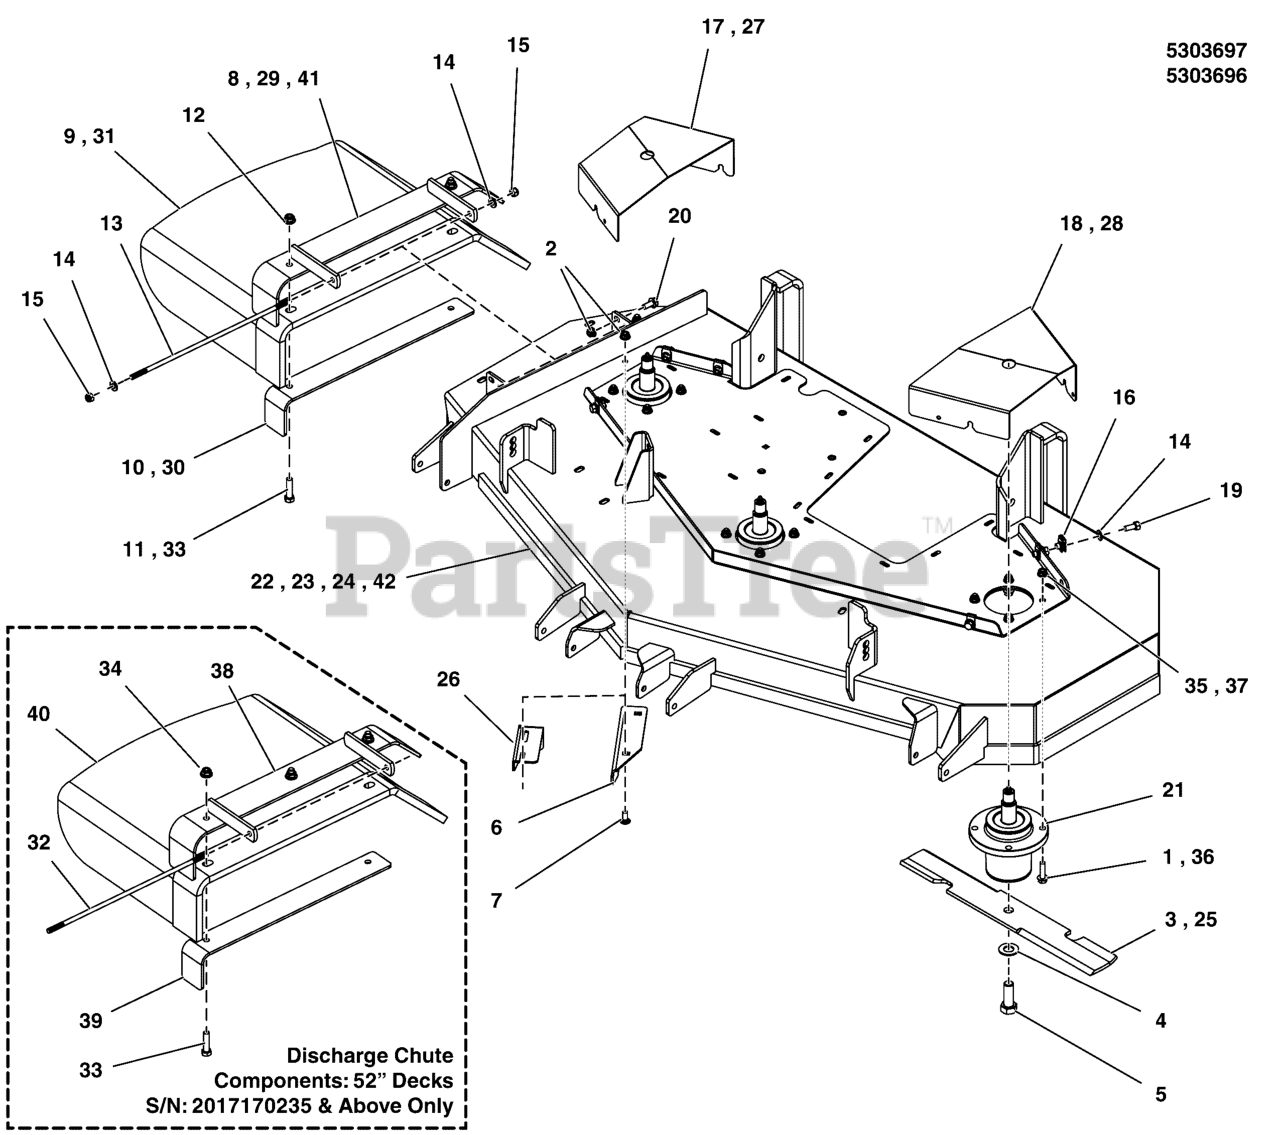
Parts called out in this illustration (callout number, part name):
1	BOLT, 5/16-18 X 1 1/4 FLANGE
2	NUT, 5/16-18 HEX NYLOCK FLANGE
3	BLADE, SET OF THREE
4	WASHER, BLADE BOLT, 9/16" F436, CZ
5	BOLT, 5/8-11 X 1-3/4 GD8
6	PLATE, DEFLECTOR, 52 DECK - BLK
7	BOLT, 5/16-18 X 3/4, CARRIAGE
8	WELD, MOUNT, DISCHARGE CHUTE - BLK
9	CHUTE, DISCHARGE, BEND RUBBER, 44/48/52 (5100842)
10	SUPPORT, DISCHARGE CHUTE, 48/52 - BLK
11	BOLT, 3/8-16 X 1-1/2" GD5 CZ
12	NUT, 3/8-16 HEX NYLOCK FLANGE
13	ROD, 5/16 X 13.75, TBE, CZ
14	WASHER, 5/16" SAE
15	NUT, 5/16-24 HEX NYLON LOCK
16	BODY CLIP, 5/16-18-7GA MATERIAL
17	GUARD, DECK, 52, RH - RED
18	GUARD, DECK, 52, LH - RED
19	BOLT, 5/16-18 X 3/4 GD5
20	BOLT, 5/16-18 X 3/4 GD5
21	ASSM, SPINDLE, LOW PROFILE
22	DECK SHELL W/ DECALS, 52, FW35 (5412132B)
23	DECK SHELL W/ DECALS, 48, FW35 (5412136B)
24	DECK SHELL W/ DECALS, 52, FW35SD-DOM (5414488B)
25	BLADES, SET OF THREE (3); 16.25 X.25 X 2.5, 1 X 3.5
26	PLATE, DEFLECTOR - BLK
27	GUARD, DECK, 48, RH - RED
28	GUARD, DECK, 48, LH -RED
29	WELD, MOUNT, DISCHARGE CHUTE - BLK
30	SUPPORT, DISCHARGE CHUTE - BLK
31	CHUTE, RUBBER DISCHARGE (5104441)
32	ROD, MOUNT, CHUTE 61, CZ
33	BOLT, 3/8-16 X 1-1/2, CARRIAGE, GD5, CZ
34	NUT, 3/8-16 HEX NYLOCK FLANGE
35	NUT, 5/16-18 HEX NYLOCK FLANGE
36	BOLT, 3/8-16 X 1-1/4, FLANGE, GD 5, CZ
37	NUT, 3/8-16 HEX NYLOCK FLANGE
38	WELD, MOUNT, DISCHARGE CHUTE - BLK
39	SUPPORT, DISCHARGE CHUTE - BLK
40	CHUTE, RUBBER DISCHARGE (5104442)
41	WELD, MOUNT, DISCHARGE CHUTE - BLK
42	DECK SHELL W/DECALS, FW35-48 (5415573B)
